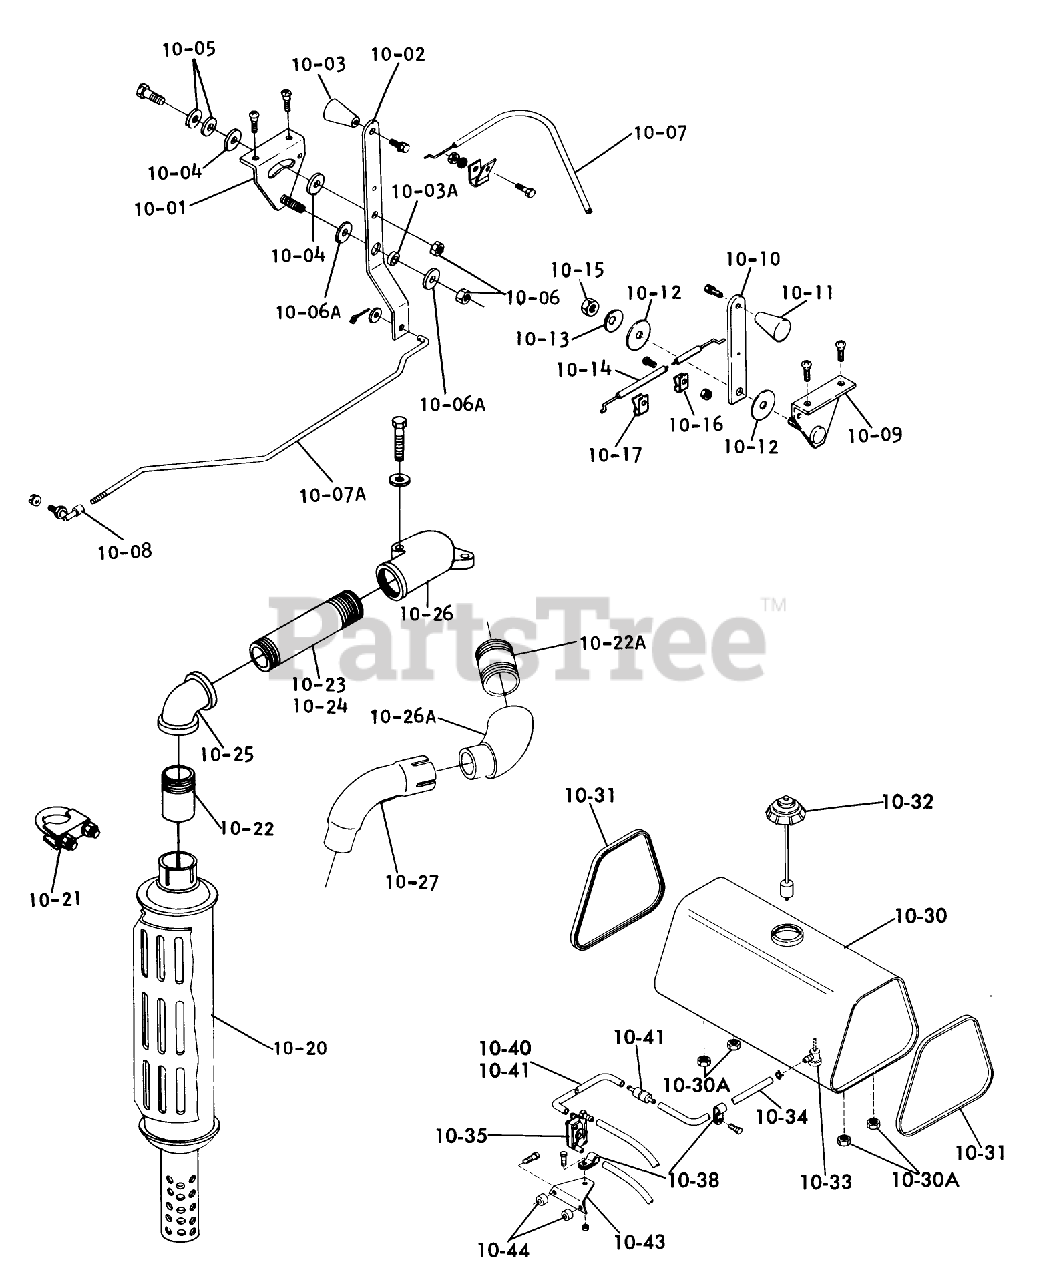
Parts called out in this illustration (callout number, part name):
10-03A	SPACER CLUTCH ARM
10-04	FRICTION WASHER
10-05	WASHER-SPRING DISC
10-06A	Washer-3/8
10-10	HANDLE
10-12	FRICTION WASHER
10-13	WASHER-SPRING DISC
10-16	CLIP BOWDEN WIRE
10-17	THROTTLE CONTROL CLP
10-20	ASSEMBLY MUFFLER
10-21	ASSY-MUFFLER CLAMP
10-22A	Nipple-Exhaust, 1 1/4 x 1-5/8, D-160
10-24	Nipple 5 in. Long
10-27	TUBE-INLET
10-32	GAUGE CAP
10-44	BEARING CAM ROLLER
